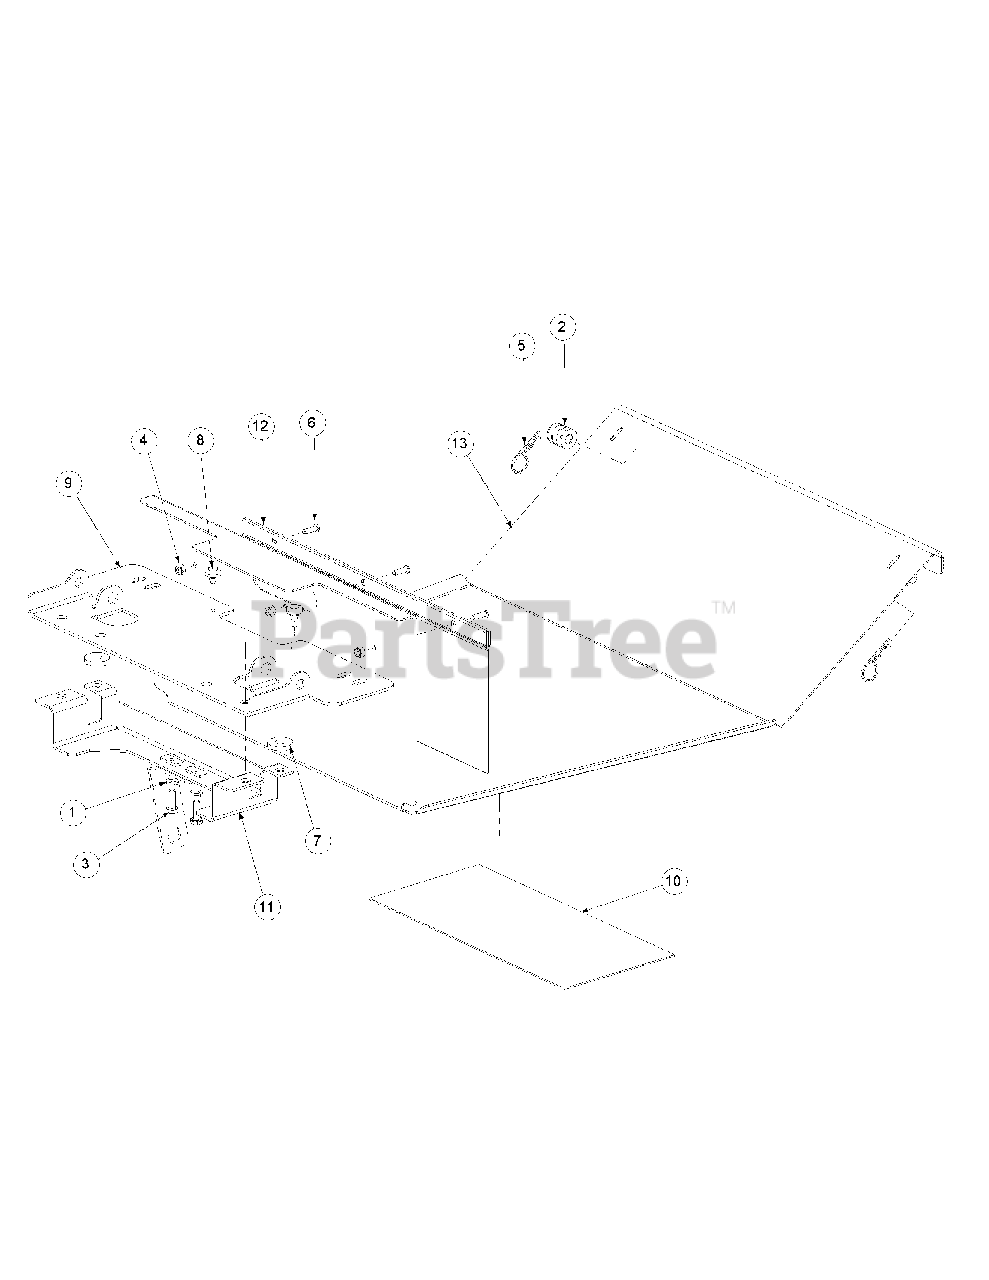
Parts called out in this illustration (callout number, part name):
1	Lock Washer, 1/4
3	Hex Cap Screw, 1/4-20, .75
4	Lock Nut, Nylon Insert, 10-32
5	Hair Pin, 3/8-1/2
6	Screw, Phillips Head, Machine, 10-32 x 5/8
7	Washer
8	Rubber Bumper, .62 OD x .22 Thick
10	Label, Belt Routing and Lubrication
11	Support, Seat Bracket
12	Bag, Debris Storage
13	Floor Panel Assembly
